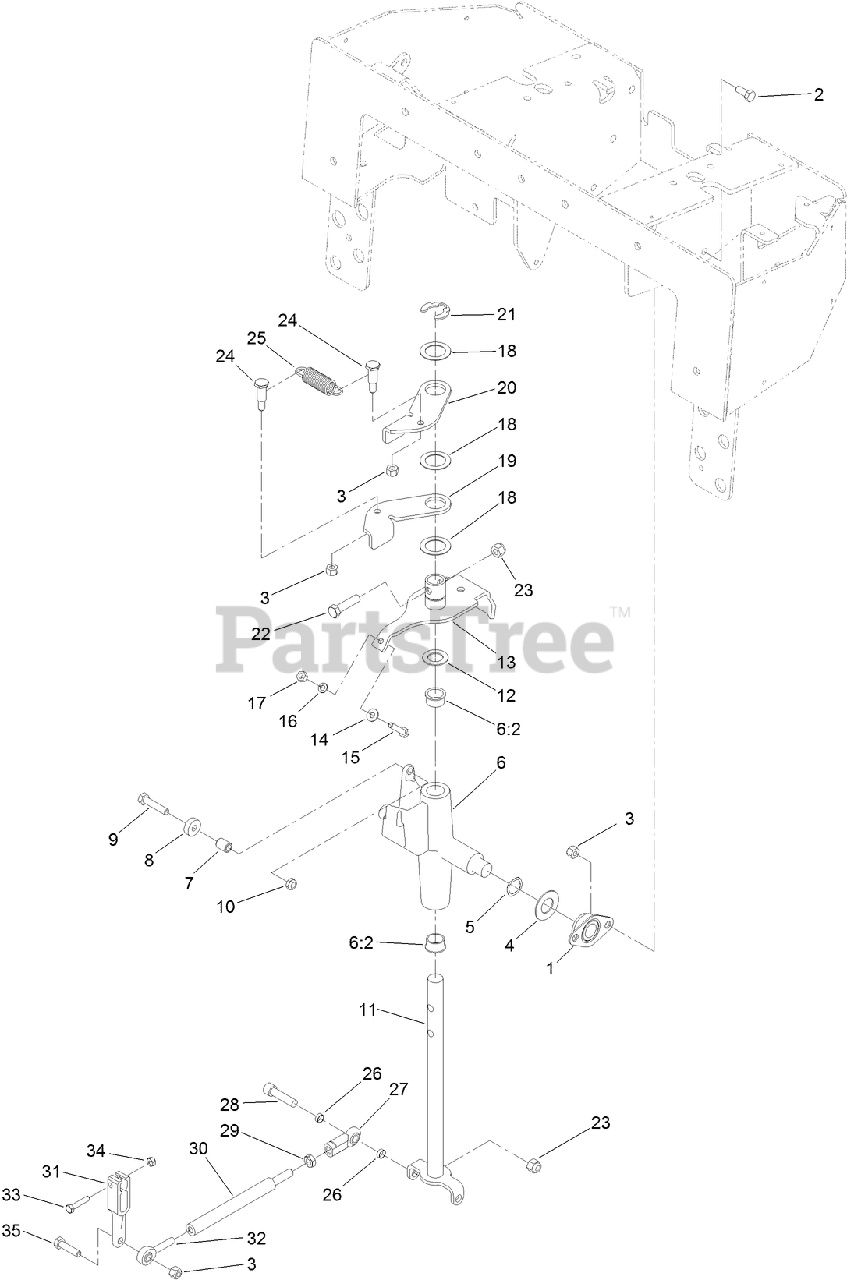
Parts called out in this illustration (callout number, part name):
1	BEARING
2	SCREW-HH
3	NUT-LOCK, NI
4	WASHER-FLAT
5	WASHER-SPRING, WAVE
6	CONTROL SUPPORT ASM
6:2	BEARING-FLANGE
7	SPACER-LEVER, CONTROL
8	BEARING-BALL
9	SCREW-HH
10	NUT-LOCK, NI
11	ROD-DRIVE
12	WASHER-THRUST
13	LEVER-PIVOT
14	WASHER-FLAT
15	SCREW-HH
16	WASHER-LOCK
17	NUT-HEX
18	WASHER-PLAIN
19	LEVER-RETURN, RH
20	LEVER-RETURN, LH
21	RING-RETAINING
22	SCREW-HH
23	NUT-LOCK, NI
24	SCREW-SHOULDER
25	SPRING-EXTENSION
26	SPACER
27	JOINT-BALL END, LH
28	SCREW-HSH
29	NUT-HEX JAM, LH
30	ROD-LINKAGE
31	ARM-CONTROL, PUMP
32	BEARING-ROD END, RH
33	SCREW-HH
34	NUT-LOCK
35	SCREW-HH
